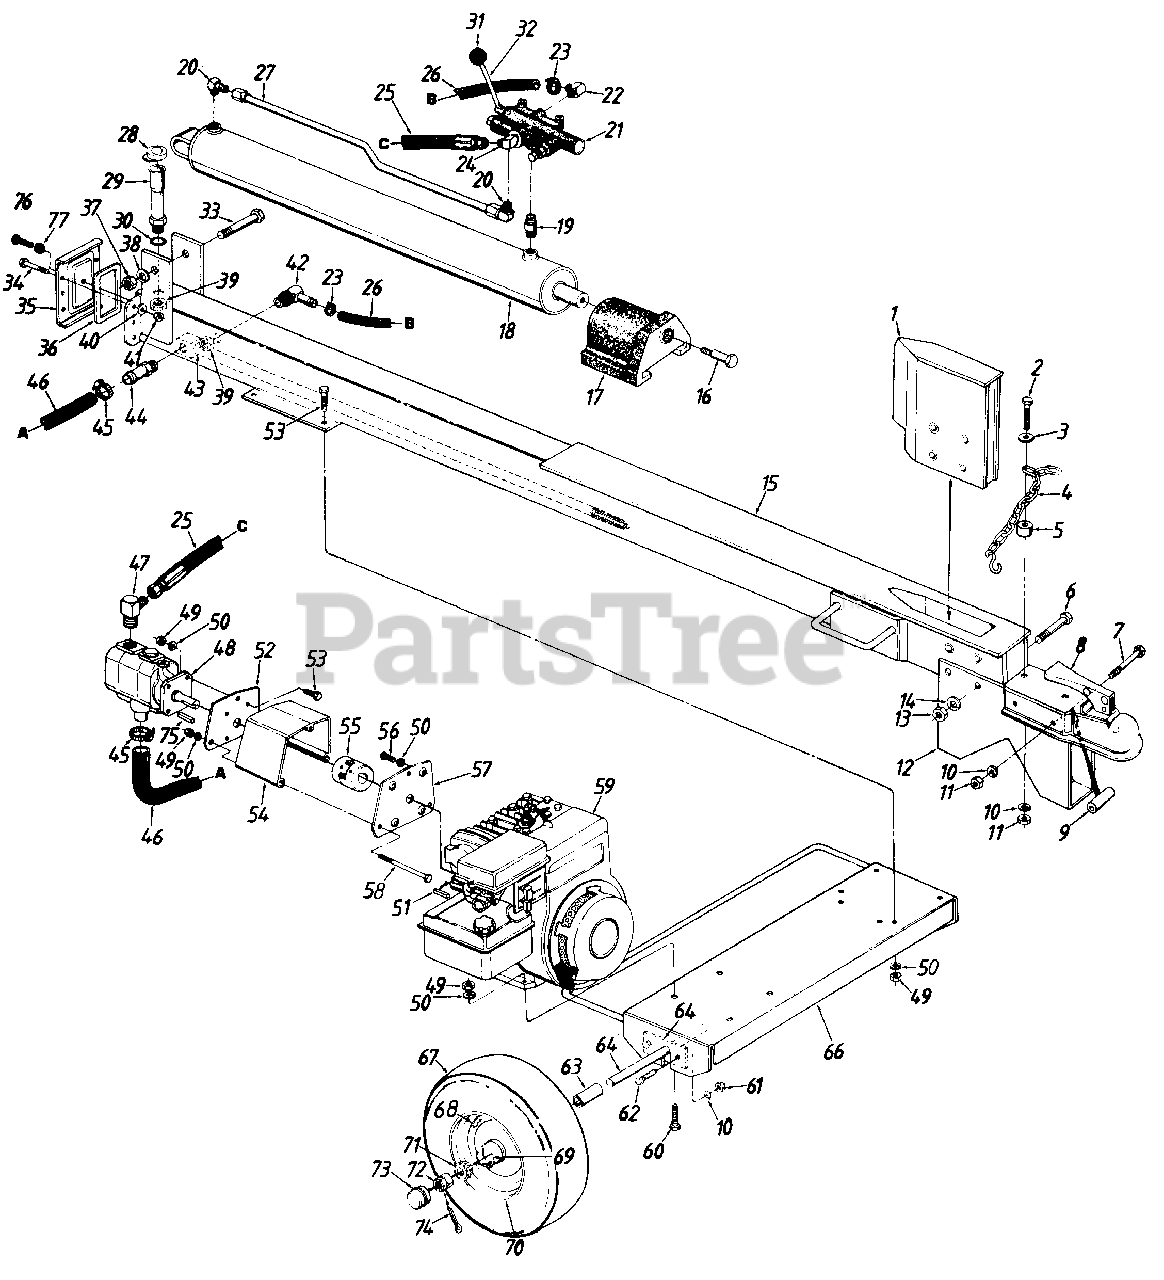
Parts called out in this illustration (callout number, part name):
1	Wedge Ass'y.
2	Hex Bolt 3/8-16 x 1.5 Lg. (Grade 5)
3	Fl-Wash. .375" I.D. x.87" O.D.
4	Chain-Tow Hitch
5	Spacer .38" I.D. x .625" O.D.
6	Hex Bolt 5/8-18 x 3.5" Lg.
7	Hex Bolt 3/8-16 x 3.25" Lg. (Grade 8)
8	Tow Hitch Ass'y.
9	Spacer .375" I.D. x .625n O.D.
10	L-Wash. 3/8" I.D.*
11	Hex Nut 3/8-16 Thd. (Grade 5)
12	Beam Stand
13	Hex Nut 5/8-18 Thd.*
14	L-Wash. 5/8" I.D.*
15	Oil Tank Ass'y.
16	Shld. Bolt .62" Dia. x .475"
17	Pusher Plate
18	638/N Hydraulic Cylinder
19	Pipe Nipple 1/2" NPT x 2" Lg.
20	90ø Solid Male Adapter
21	Control Valve
22	Return Elbow
23	Adjustable Hose Clamp
24	90ø Solid Male Adapter
25	High Pressure Hydraulic Hose 29.5n Lg.
26	Return Hose 3/4" I.D. x 231/2" Lg.
27	Metai Pressure Tube
29	Filler Tube Ass'y.
30	"O"-Ring .92" I.D.
31	Ball Knob
32	Control Handle
33	Hex Bolt 3/4-10 x 4.5" Lg.
34	Hex Bolt 5/16-18 x 1.5" Lg.*
35	Beam End Plate
36	Gasket
37	Hex Nut 3/4-10 Thd.*
38	L-Wash. 3/4" I.D.*
39	Hex Nut 1-1/16-12 Thd.
40	Fl-Wash. .341" I.D. x .68" O.D.
41	Hex L-Nut 5/16-18 Thd.
42	90ø Adapter 3/4" Hose
43	Strainer Tube Ass'y.
44	Adapter 1" x 1-1/16-12 Thd.
45	Hose Clamp 5/8"
46	Suction Hose 1" I.D.
47	90ø Adapter
48	Two Volume Pump
49	Hex Nut 5/16-24 Thd.
50	L-Wash. 5/16" I.D.
51	Sq. Key 3/16 x 75" Lg.
53	Hex Bolt 5/16-24 x 1 on Lg.*
54	Coupling Shield
55	Flexible Coupling
56	Hex Bolt 5/16-24 x .62" Lg.
58	Hex Bolt 5/16-24 x 4.0" Lg.
59	Engine
60	Hex Bolt 5/16-24 x 1.75" Lg.
61	Hex Nut 3/8-24 Thd.
62	Hex Bolt 3/8-24 x 1.0" Lg.
63	Spacer .75" I.D. x 1.12" O.D.
64	Axle Assembly
66	Engine Frame Ass'y.
68	Air Valve
69	Bearing Seal
71	Roller Bearing w/Race
72	Hex Slotted Nut 3/4-16 Thd.
73	Hub Cap
74	Cotter Pin 5/32" Dia.
75	Hi-Pro Key 1/8" x 1/2" Lg.
76	Hex TT-Tap Scr. 5/16-18 x .62" Lg.
77	Gasket Washer 5/16" I.D. x 3/4" 0 D
